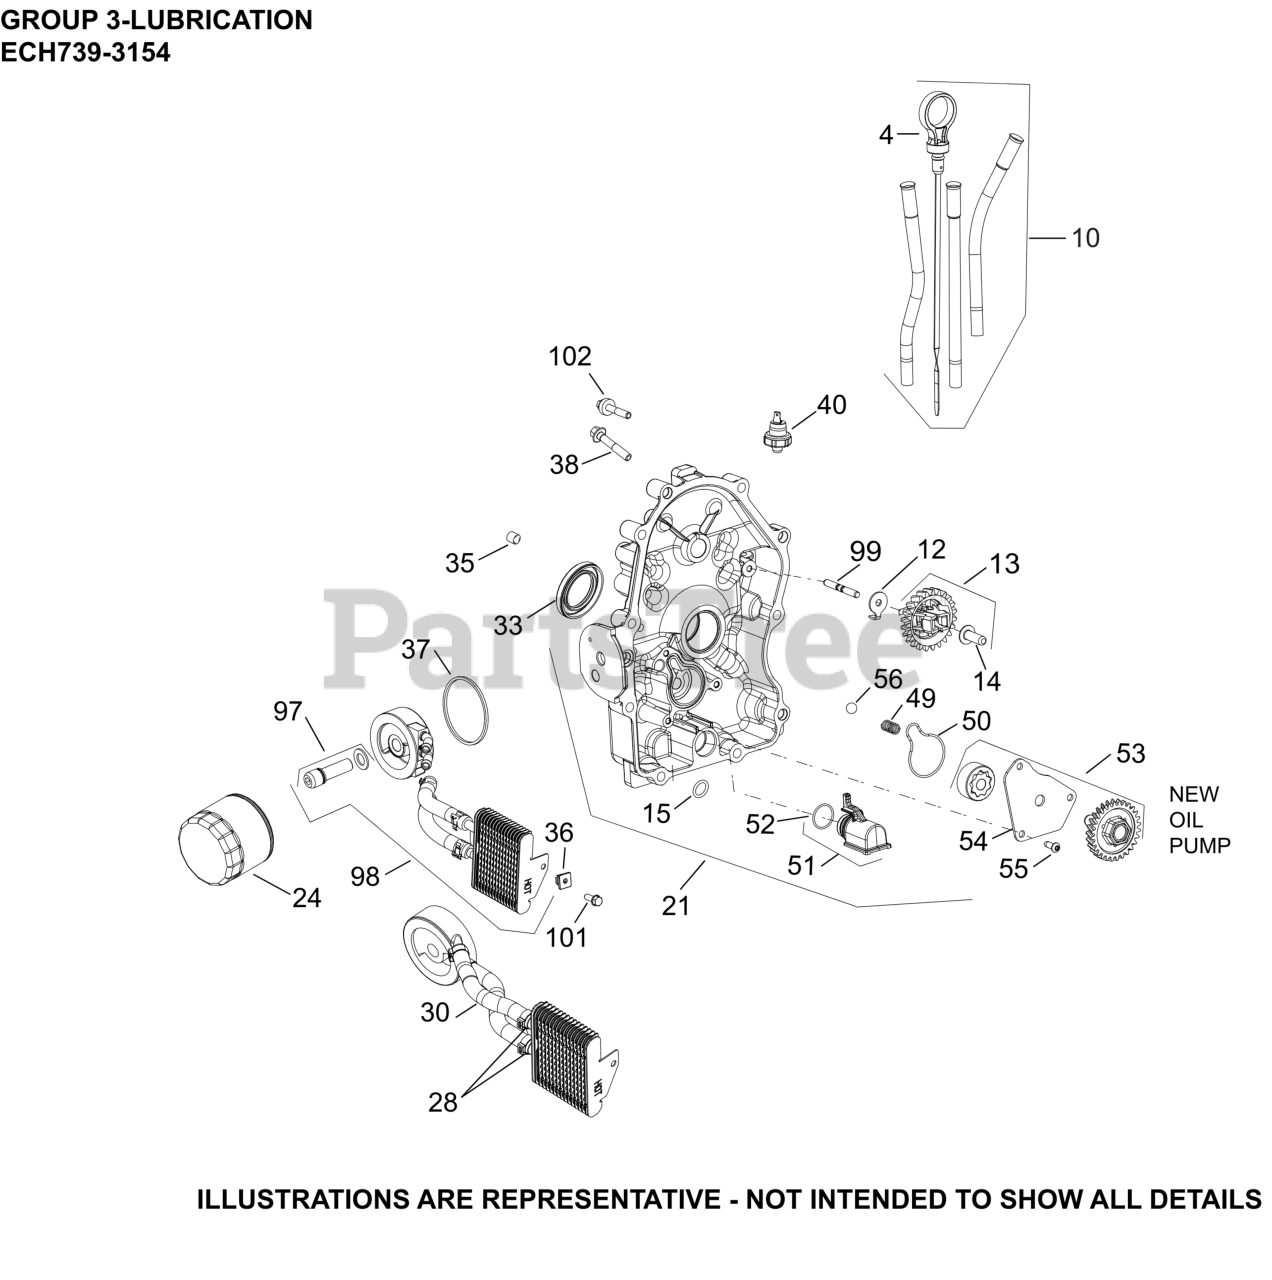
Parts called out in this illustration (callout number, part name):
10	KIT, DIPSTICK/DIPSTICK TUBES
12	TAB, LOCKING
13	KIT, GOVERNOR GEAR W/PIN
14	PIN, GOVERNOR REGULATING
21	KIT, CLOSURE PLATE ASSY
24	OIL FILTER
28	CLAMP, HOSE LOW PROFILE
30	KIT, HOSE 140MM
35	PLUG, CTSK PIPE 1/8"
36	NUT, PLASTIC - BLACK
37	O-RING, OIL COOLER
38	SCREW, FLG M8X1.25X45
38	SCREW, HEX FLANGE
40	SENSOR, OIL PSI
49	SPRING, COMPRESSION
50	SEAL, OIL PUMP COVER
51	PICK-UP ASSEMBLY, OIL
52	O-RING, OIL PICK-UP
53	PUMP ASSEMBLY, OIL
54	COVER, OIL PUMP
55	SCREW, BUTTON HEAD
56	PRESSURE RELIEF BALL
97	KIT, OIL FILTER NIPPLE
98	KIT, OIL COOLER
99	SHAFT, GOVERNOR GEAR
101	SCREW, HEX HEAD
102	WASHER, FLAT
